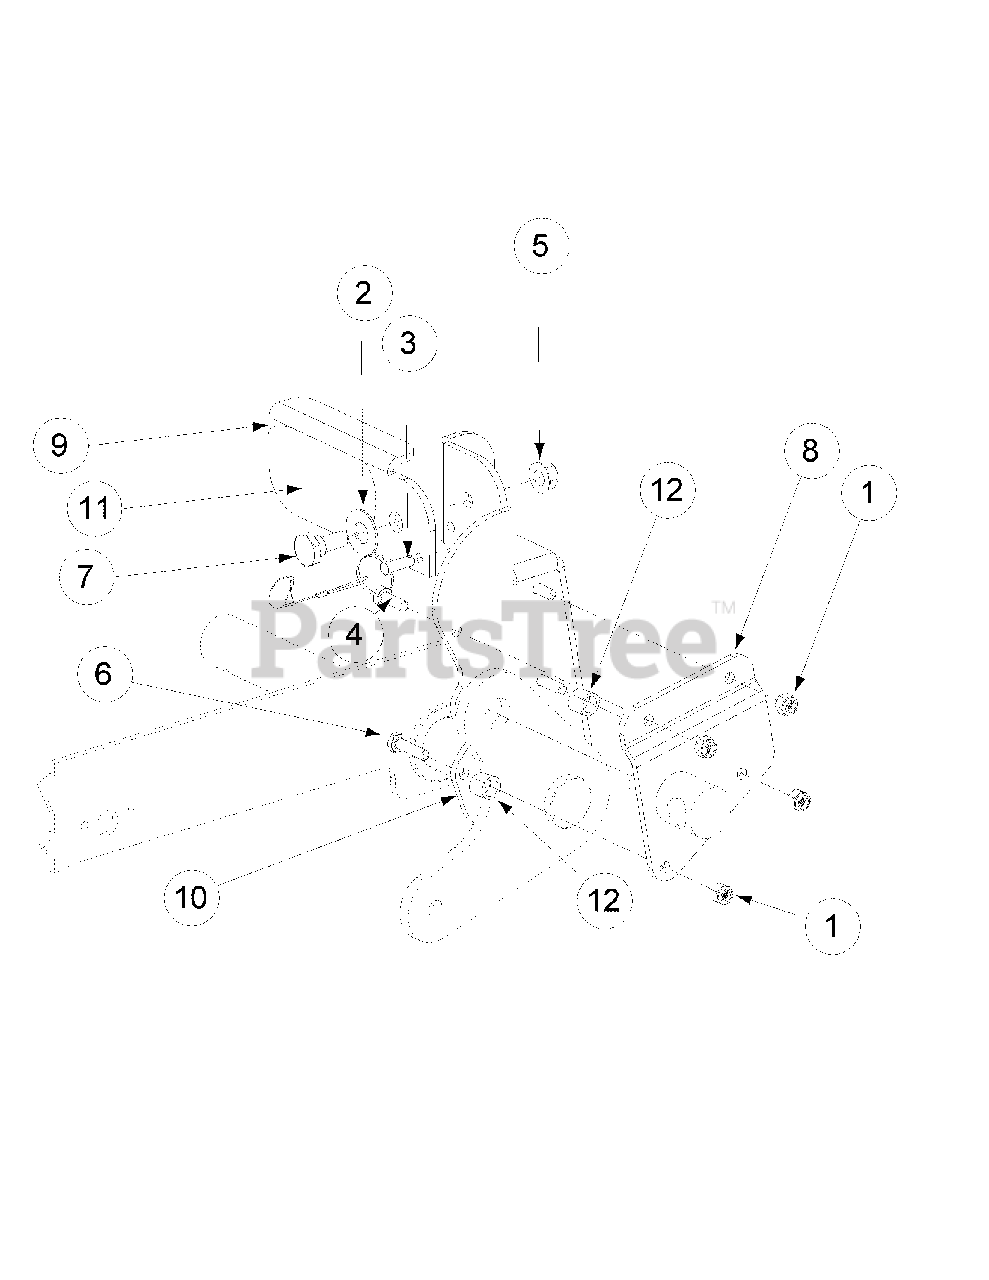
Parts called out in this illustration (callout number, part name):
1	Lock Nut, Nylon Insert, 1/4-20
2	Washer, 1/2 x 1 Shim
3	Detent Pin w/12" Lanyard
4	Hex Cap Screw, 1/4-20, .75
5	Hex Nut, Flange Lock 3/8-16
6	Hex Cap Screw, 1/4-20, 1.00
7	Shoulder Screw, .50 x .27 Lg., 3/8-16
8	Foot Lift Backup Pedal
9	Deck Foot Pedal Lift
10	Deck Foot Pedal Lift
11	Deck Foot Lift Pad
12	Turnbuckle Sleeve
